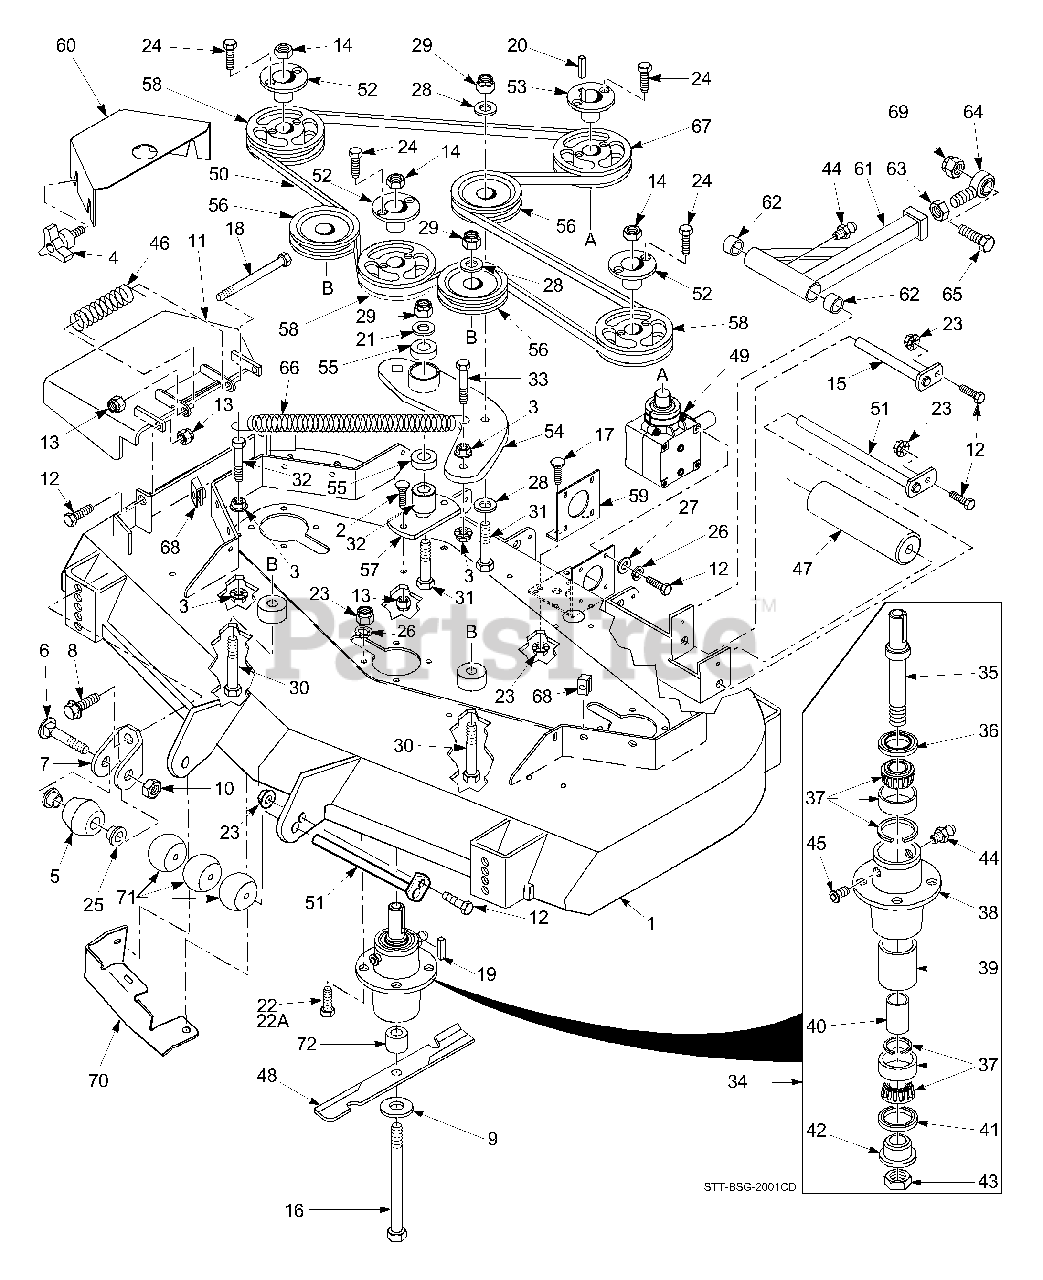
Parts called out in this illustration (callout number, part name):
1	Cutter Deck, 61" Advantage
1	Cutter Deck, 72" Advantage
2	Bolt, Carriage 5/16-18 x 1"
3	Nut, Hex Serrated Flange 3/8-16
4	Wing nut, 3/8-16
5	Anti-Scalp Wheel
6	Bolt, Carriage 3/8-16 x 4"
7	Anti-Scalp Wheel Bracket
8	Bolt, Hex Serrated Flange 3/8-16 x 1"
9	Flatwasher, 5/8" (.688 x 1.75 x .134)
10	Locknut, 3/8-16 Center Lock
11	Discharge Chute, 61" & 72" Adv.
12	Bolt, Hex Head 5/16-18 x 1.75" (Front)
13	Nut, Hex Elastic Stop 5/16-18
14	Nut, 5/8-11 UNC
15	Push Arm Shaft
16	Bolt, Hex Head 5/8-11 x 9.50"
17	Bolt, Carriage 5/16-18 x .75"
18	Bolt, Hex Head 5/16-18 x 4.75"
19	Key, 1/4 x 1/4 x 2"
20	Key, 1/4 x 1/4 x 1.25"
21	Flatwasher,3/8-.39 x .938 x .105 HD
22	Bolt, Hex Head 5/16-18 x 1.50"
22A	Bolt, Hex Head 5/16-18 x 1.75"
23	Nut, Hex Serrated Flange 5/16-18
24	Bolt, Hex Head 1/2-20 x .75"
25	Bushing, .376 I.D. Oilite
26	Lockwasher, 5/16"
27	Flatwasher, 5/16" (.375 x .875 x .083)
28	Flatwasher, 3/8" (.391 x .938 x .105)
29	Nut, Hex Elastic Stop 3/8-16
30	Bolt, Hex Head 3/8-16 x 3.25"
31	Bolt, Hex Head 3/8-16 x 2.50"
32	Pivot, Idler - Short
33	Bolt, Hex Head 3/8-16 x 1.50" Grade 8
34	Spindle Assembly
35	Spindle Shaft
36	Seal, Top
37	Bearing Assembly
38	Spindle Housing
39	Spacer, Outside
40	Spacer, Inside
41	Seal, Bottom
42	Spindle Bushing, Bottom
43	Nut, Special 1 - 1/16-18
44	Grease Fitting
45	Relief Fitting, Tapered Spindle
46	Spring, Discharge Chute
47	Guide, Roller
48	Cutter Blade, 21.0" 61"
48	Cutter Blade, 24.5" 72"
49	Gearbox Assembly, Deck Drive
50	Belt, Cutter Deck Drive, 61"
50	Belt, Cutter Deck Drive, 72"
51	Roller Shaft
52	Tapered Hub, 1-1/8" Bore
53	Tapered Hub, 1" Bore
54	Idler Arm, Cutter Deck
55	Bearings, Ball
56	Pulley, Idler
57	Base, Idler Pivot
58	Pulley, 6.35 O.D. - 61"
59	Mounting Plate, Gearbox
60	Belt Cover, LH - 61"
61	Pusharm
62	Spacer
63	Nut, Hex Head 5/8-18 UNF
64	Rod End, 5/8" Male RH Thread
65	Bolt, Hex Head 5/8-11 x 4-1/2"
66	Spring, Cutter Deck
67	Pulley, 6.35 O.D. - 61"
68	U-Nut, 3/8-16
69	Nut, Hex Elastic Stop 5/8-11
70	Discharge Baffle 61"
71	Guide Roller
72	Spacer, Spindle
04001.11	Bolt, Hex Head 5/16-18 x 1.50" (Rear)
